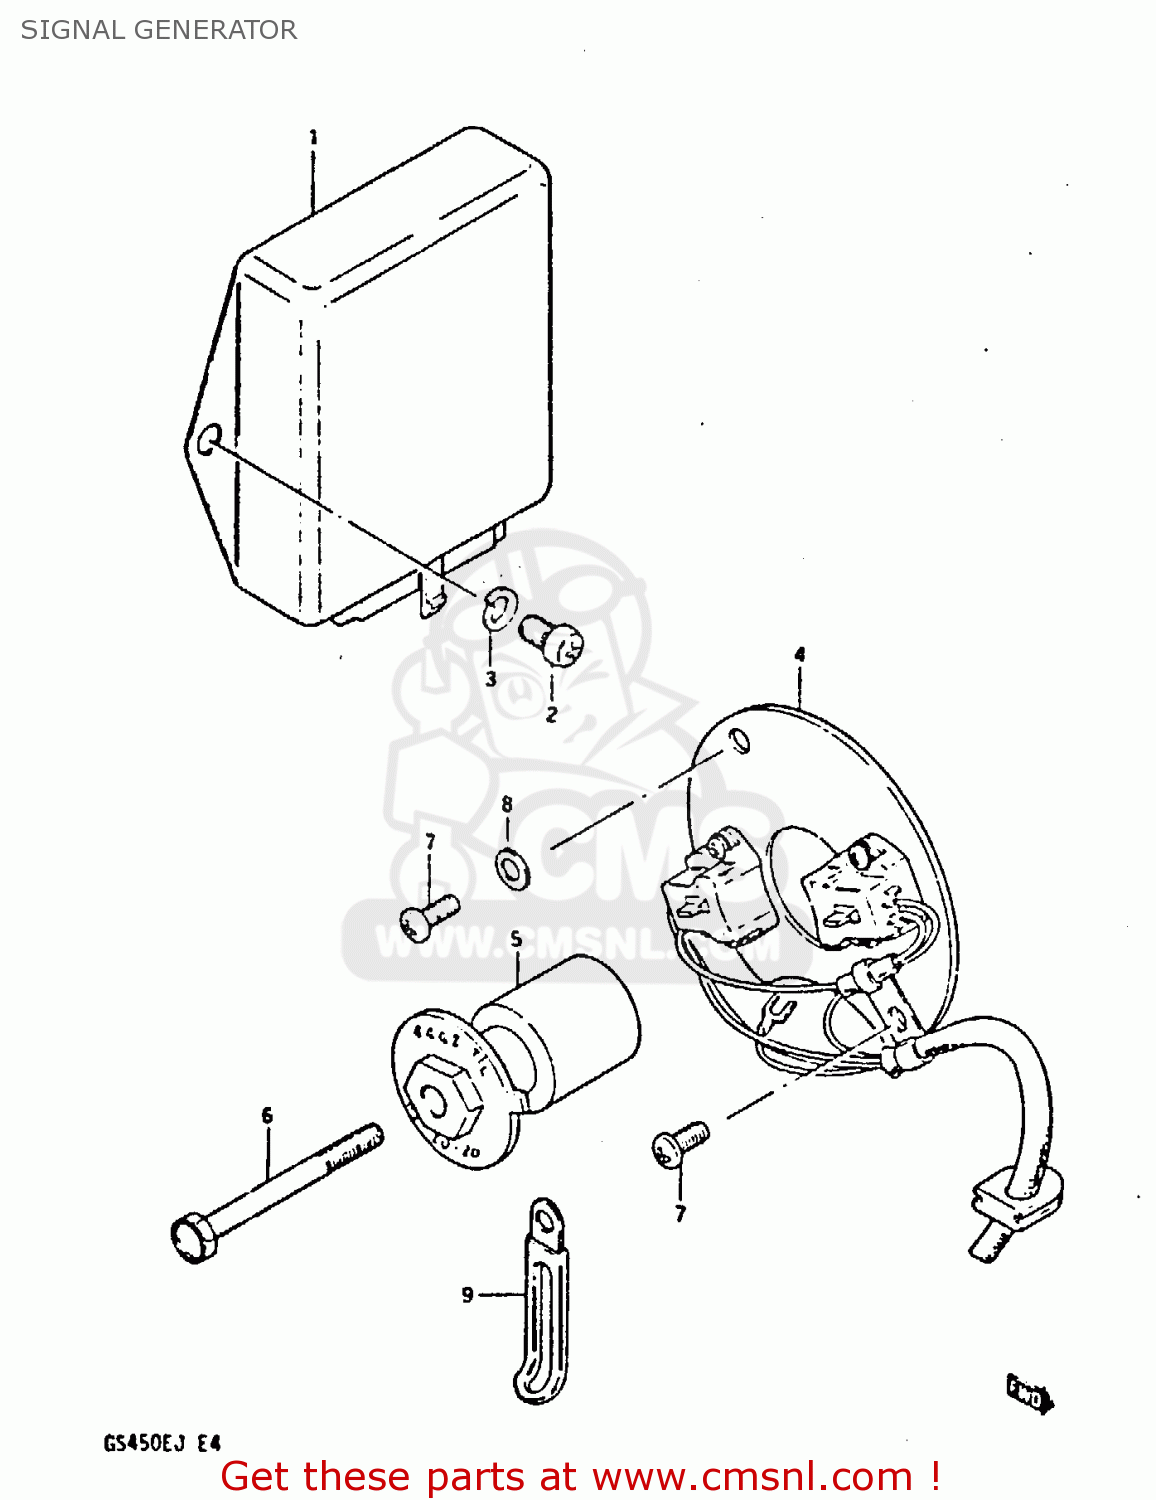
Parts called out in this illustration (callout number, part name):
1	IGNITOR UNIT
2	SCREW
3	WASHER,LOCK
4	SIGNAL GENERATOR ASSY
5	ROTOR,SIGNAL
6	BOLT 6X60
7	SCREW(5X12)
8	WASHER(5.5X10X0.8)
9	CLAMP L:35
